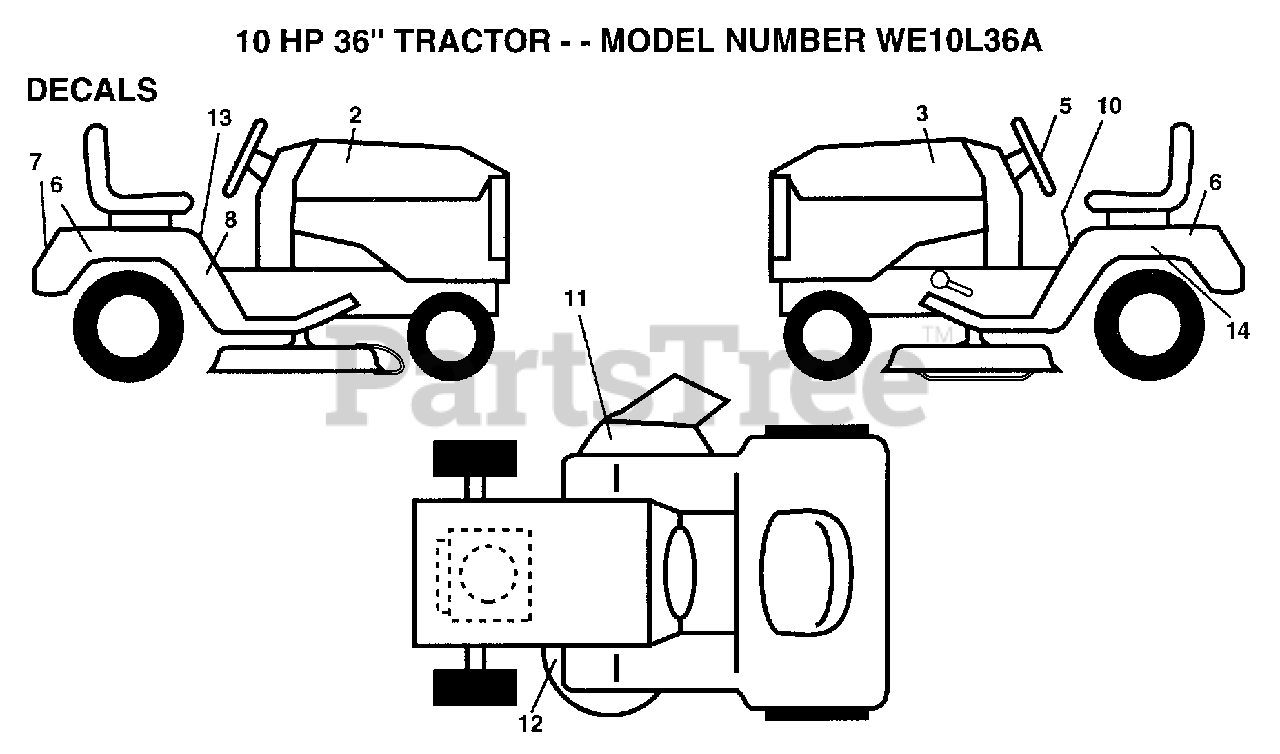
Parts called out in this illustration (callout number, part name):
2	DECAL.STRIPE.RH
3	DECAL.STRIPE.LH
5	DECAL.WHL.STRG.
6	DECAL.FEND.QUICKS
7	DECAL.FENDER
8	DECAL.CENTER.SHIF
11	"DECAL, WARNING"
12	DECAL.V.BELT
13	DECAL CAUTION
14	DECAL
